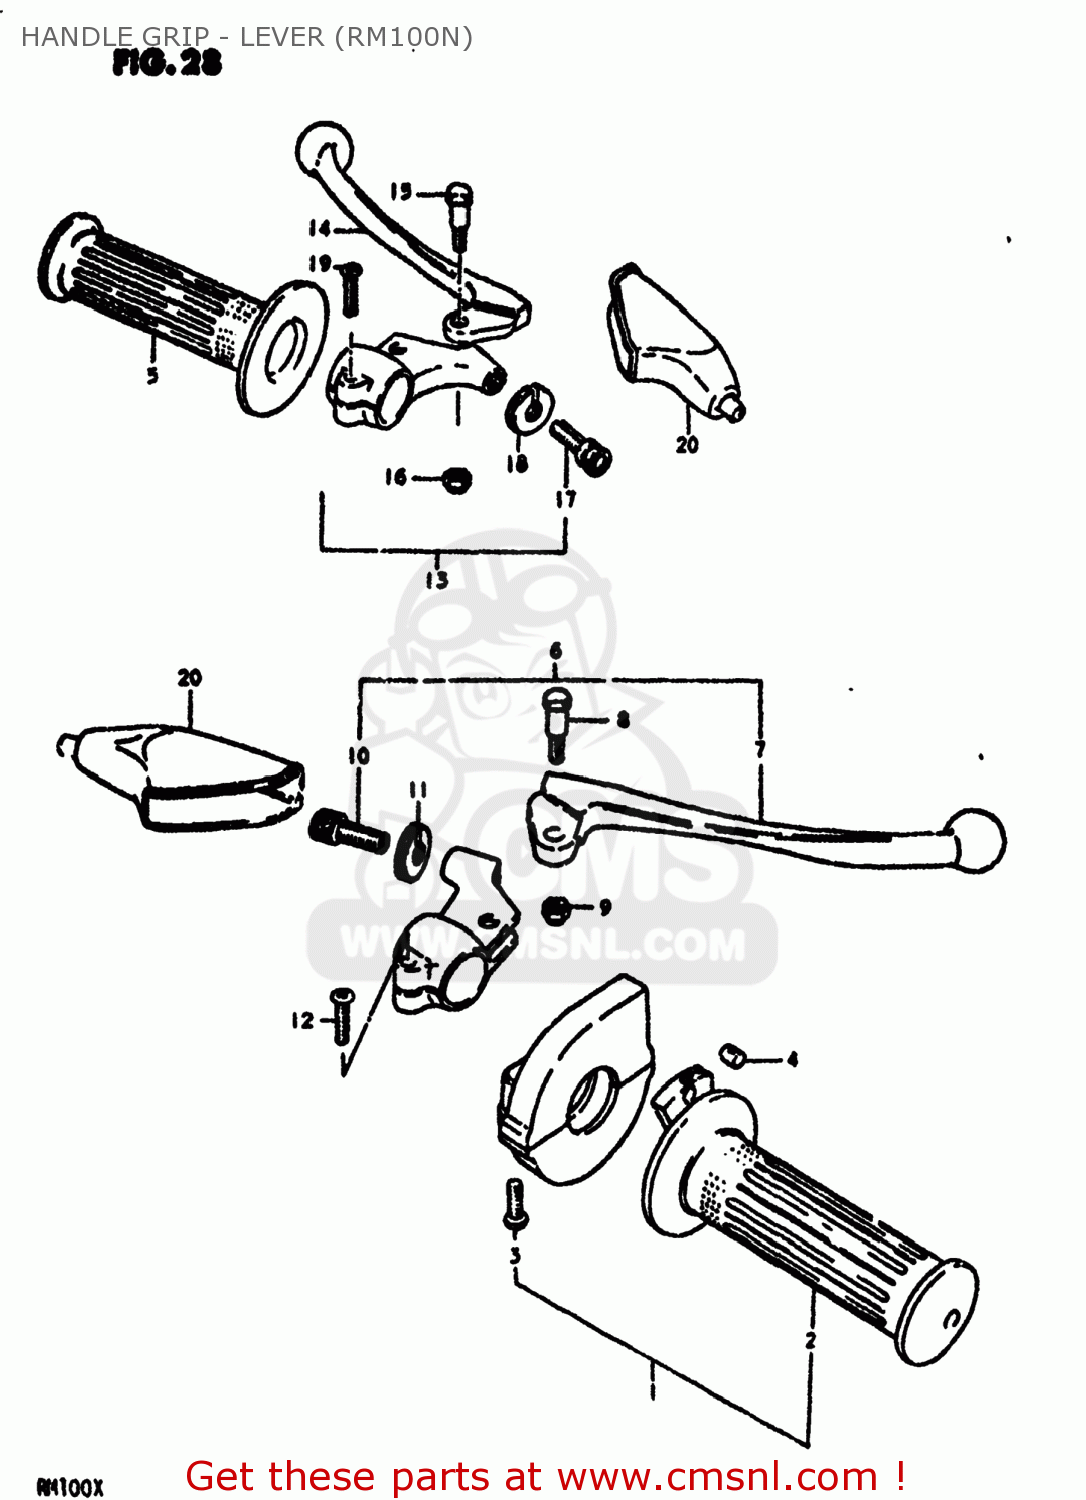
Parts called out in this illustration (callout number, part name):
1	GRIP ASSY,THROTTLE
2	GRIP,THROTTLE
3	SCREW
4	PIECE,THROTTLE END
5	GRIP,LEFT
6	LEVER ASSEMBLY,BRAKE
7	LEVER,BRAKE
8	BOLT,LEVER
9	NUT 6MM
10	ADJUSTER,CABLE
11	NUT,CABLE ADJUSTER
12	SCREW
13	LEVER ASSY,CLUTCH
14	LEVER,CLUTCH
15	BOLT,LEVER
16	NUT 6MM
17	ADJUSTER,CABLE
18	NUT,CABLE ADJUSTER
19	SCREW
20	COVER,CLUTCH LEVER
